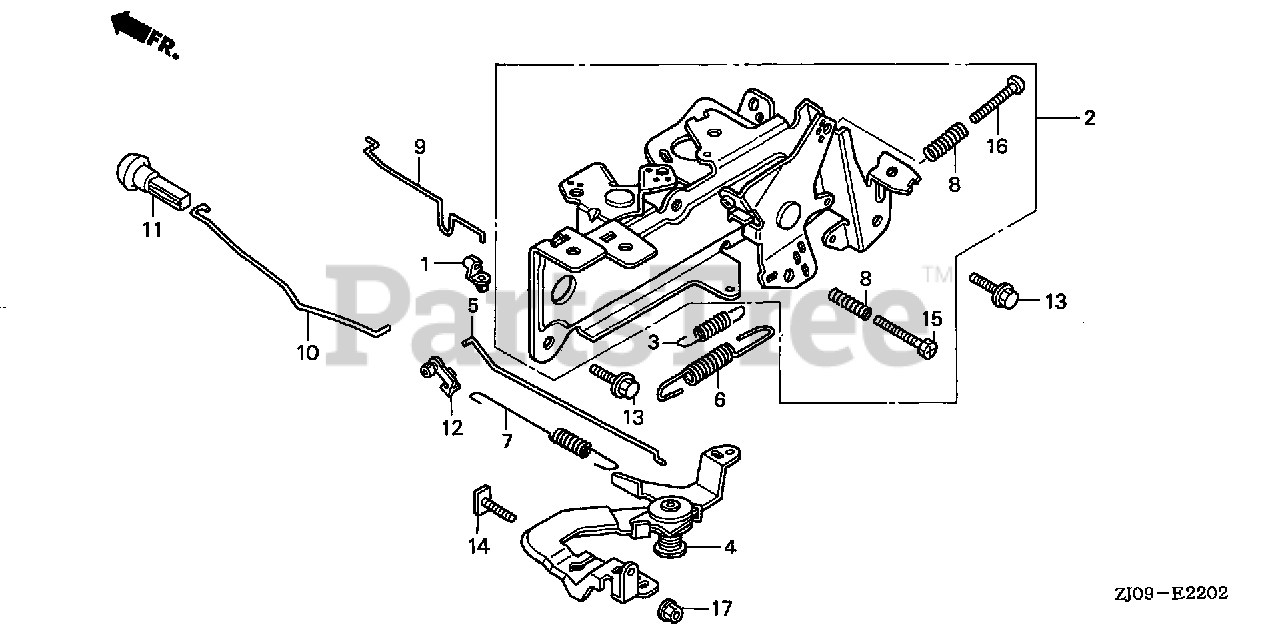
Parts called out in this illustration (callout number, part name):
1	JOINT, ROD
2	CONTROL ASSY. (AUTO THROTTLE)
3	SPRING, STARTER
4	ARM, GOVERNOR
5	ROD, GOVERNOR
6	SPRING, GOVERNOR (MANUAL)
7	SPRING, THROTTLE RETURN
8	SPRING, CONTROL ADJUSTING
9	ROD, CHOKE CONTROL
10	ROD, CHOKE KNOB
11	KNOB, CHOKE
12	BUSH, LINKAGE
13	BOLT, FLANGE (6X14)
14	BOLT, GOVERNOR ARM
15	BOLT, SLOT (5X25)
16	SCREW, PAN (5X35)
17	NUT, FLANGE (6MM)
